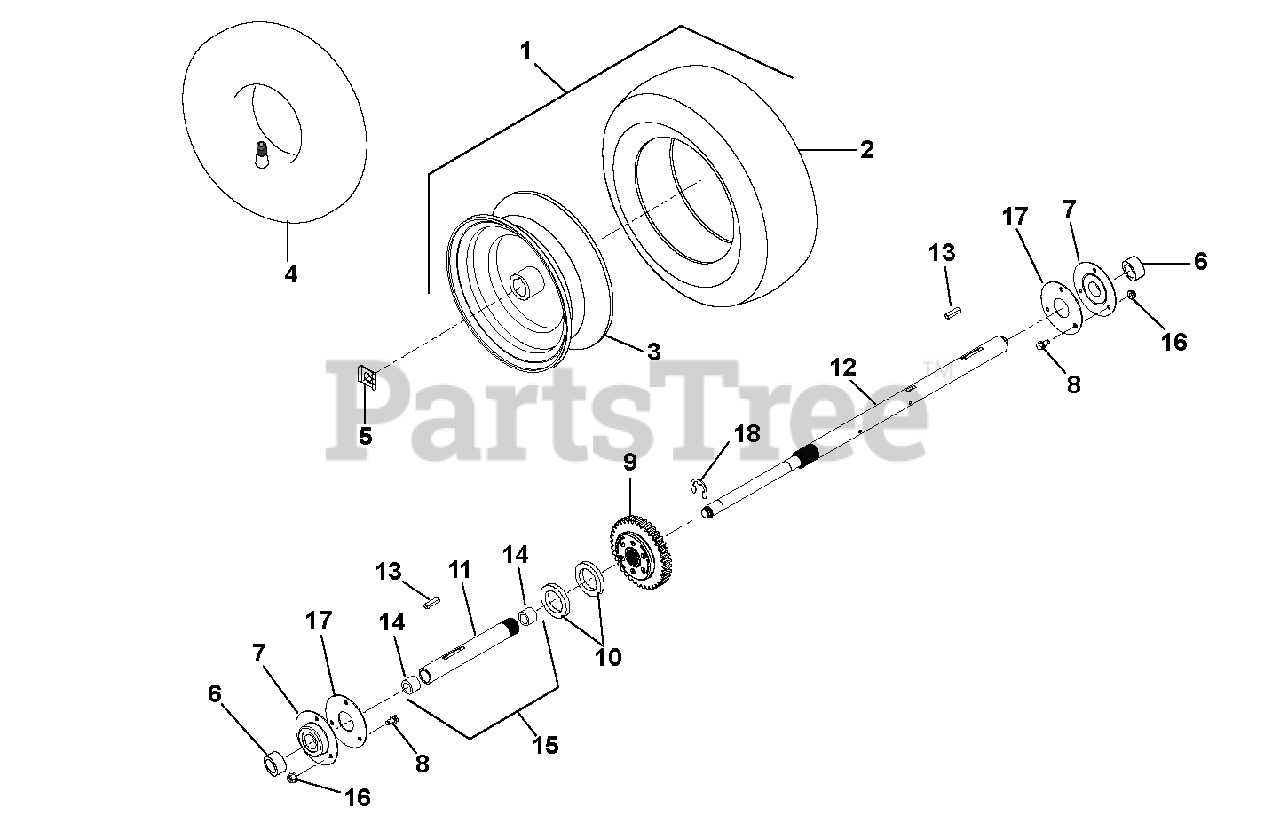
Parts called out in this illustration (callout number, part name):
1	TIRE/WHEEL, RH 16X6.50-8 DIFF
2	TIRE, 16X6.50-8 K478
3	HUB, WHEEL - 16X6.5-8 DIFF
5	CLIP, SNAP .625 DIA
6	SPACER, PRO AXLE BEARING
7	BRG-FLG 1.003/1.000 3 BOLT
8	@BLT-HEX .25-20X.75 GR5 YWZC
9	DIFFERENTIAL, AUTOMATIC
10	WSHR-FL-STL- 1.062X2.0X.134 YZ
11	AXLE, SHORT-PRO AUTO DIFF
12	AXLE, LONG-PRO AUTO DIFF
13	KEY-RECT .25X.188X1.00
14	BSHG-SLV .706X.764X.75 BRZ
15	AXLE, SHORT-AUTO W/BUSHINGS
16	@NUT-LK-CTR-FLG .25-20 YWZC
17	PLATE, BEARING SPACER
18	RG-RTNG-EXT .625X.042
